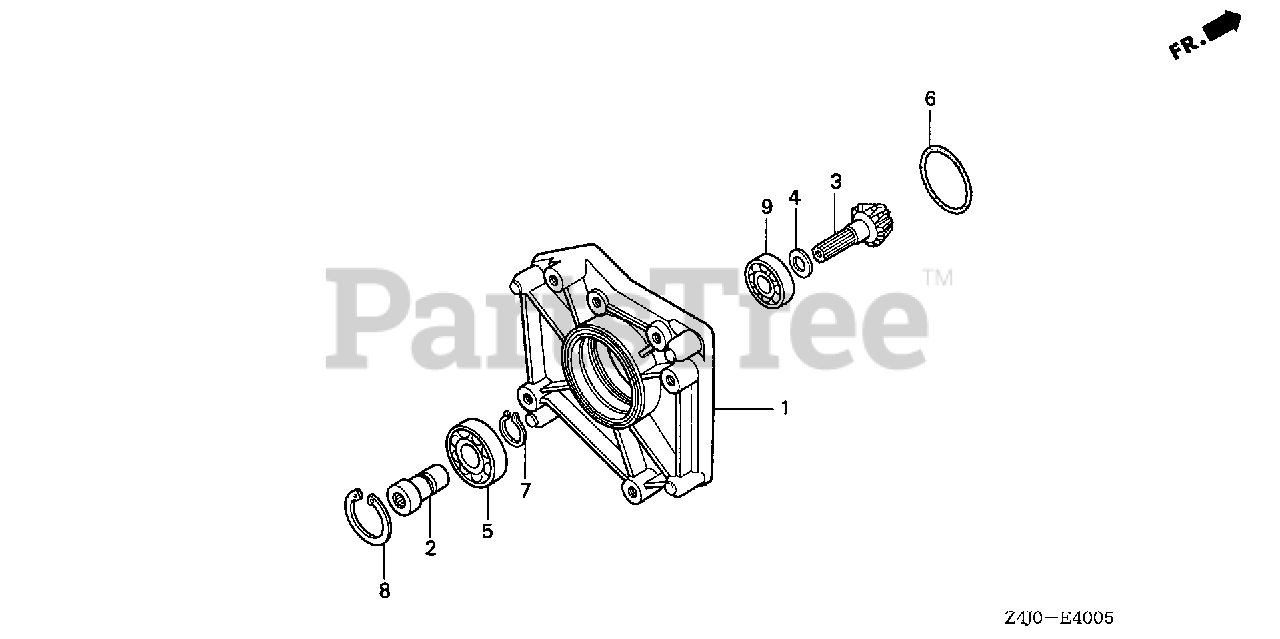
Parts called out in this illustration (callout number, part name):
1	COVER, BEVEL
2	SHAFT, JOINT
3	PINION, BEVEL
4	WASHER, BEVEL GEAR
5	BEARING, RADIAL BALL
6	O-RING (42.5X3)
7	CIRCLIP (OUTER) (22MM)
8	CIRCLIP (INNER) (50MM)
9	BEARING, RADIAL BALL (6203)
